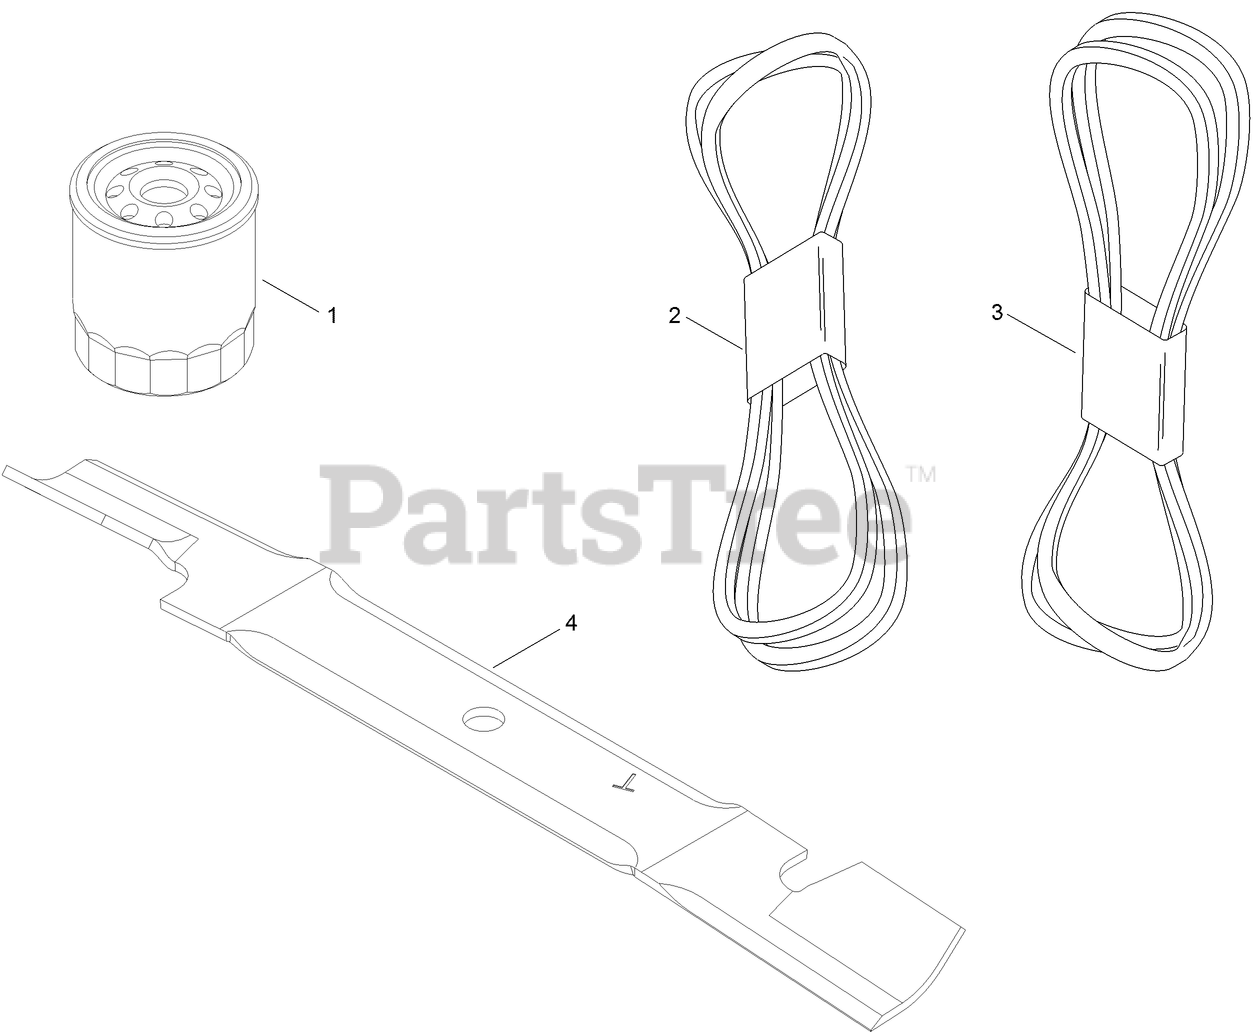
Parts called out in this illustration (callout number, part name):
1	ELEMENT-OIL FILTER, HYD
2	V-BELT
3	V-BELT
4	BLADE-HI FLO
